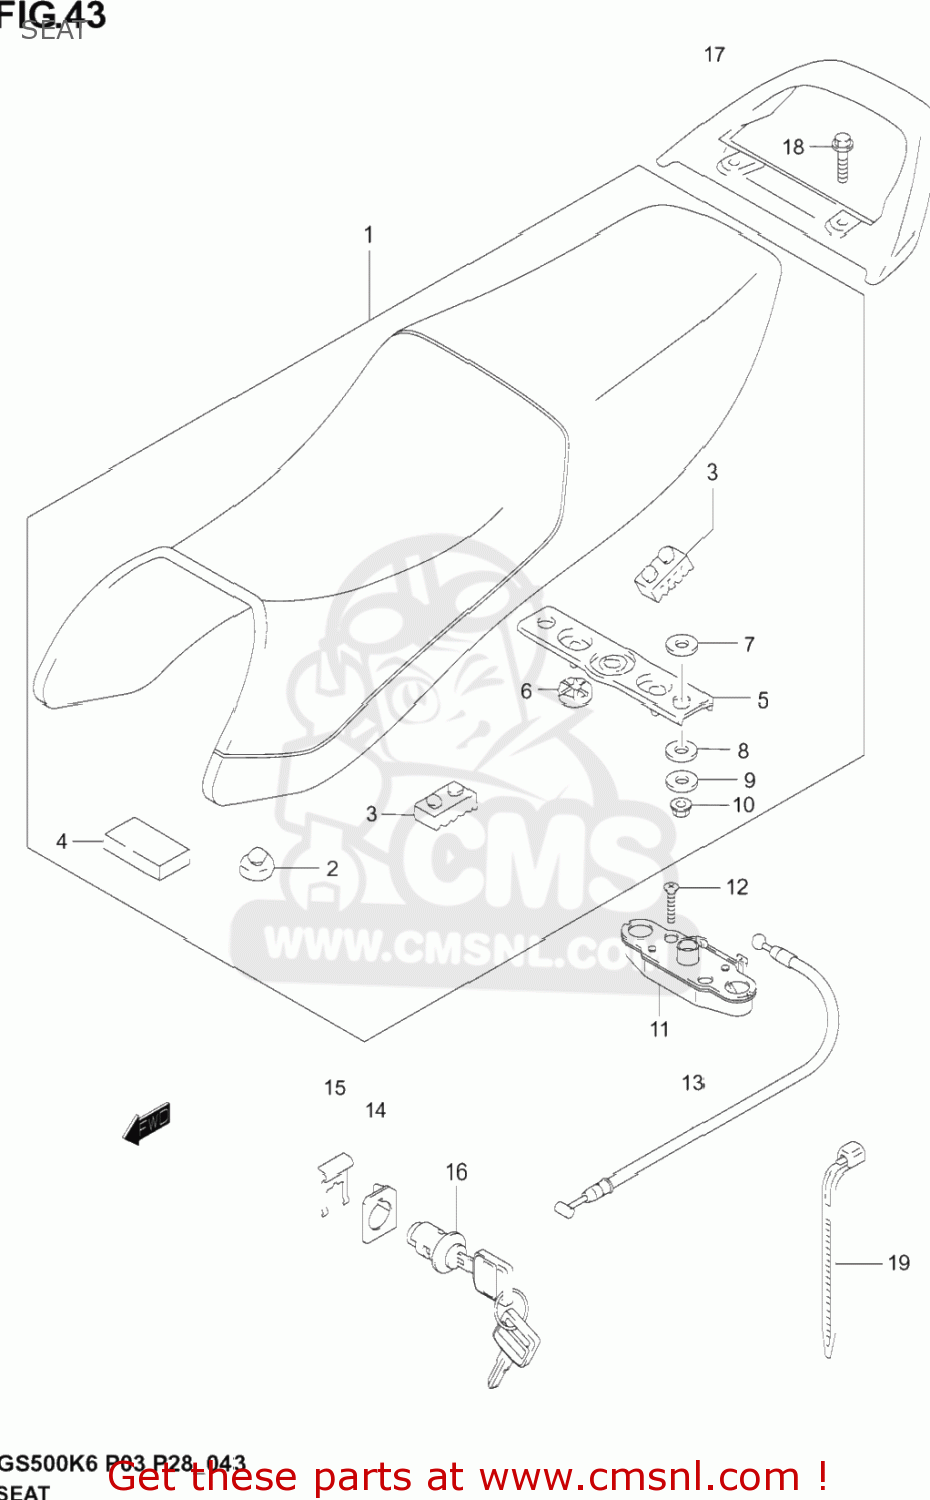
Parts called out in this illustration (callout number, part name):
2	CUSHION,FRONT
3	CUSHION,RR
4	CUSHION, BATTERY STOPPER
5	STRIKER, SEAT LOCK
6	CUSHION, BOSS
7	CUSHION, STRIKER UPPER
8	CUSHION, STRIKER LOWER
9	WASHER
10	NUT
11	BRACKET,SEATSU
12	BOLT
13	CABLE, SEAT LOCK
14	GUIDE,SEAT LOCK CABLE
15	PLATE,SEAT LOCK ASSY
16	LOCK SET,SEAT
17	HANDLE, PILLION RIDER (BLACK)
18	BOLT
19	CLAMP
